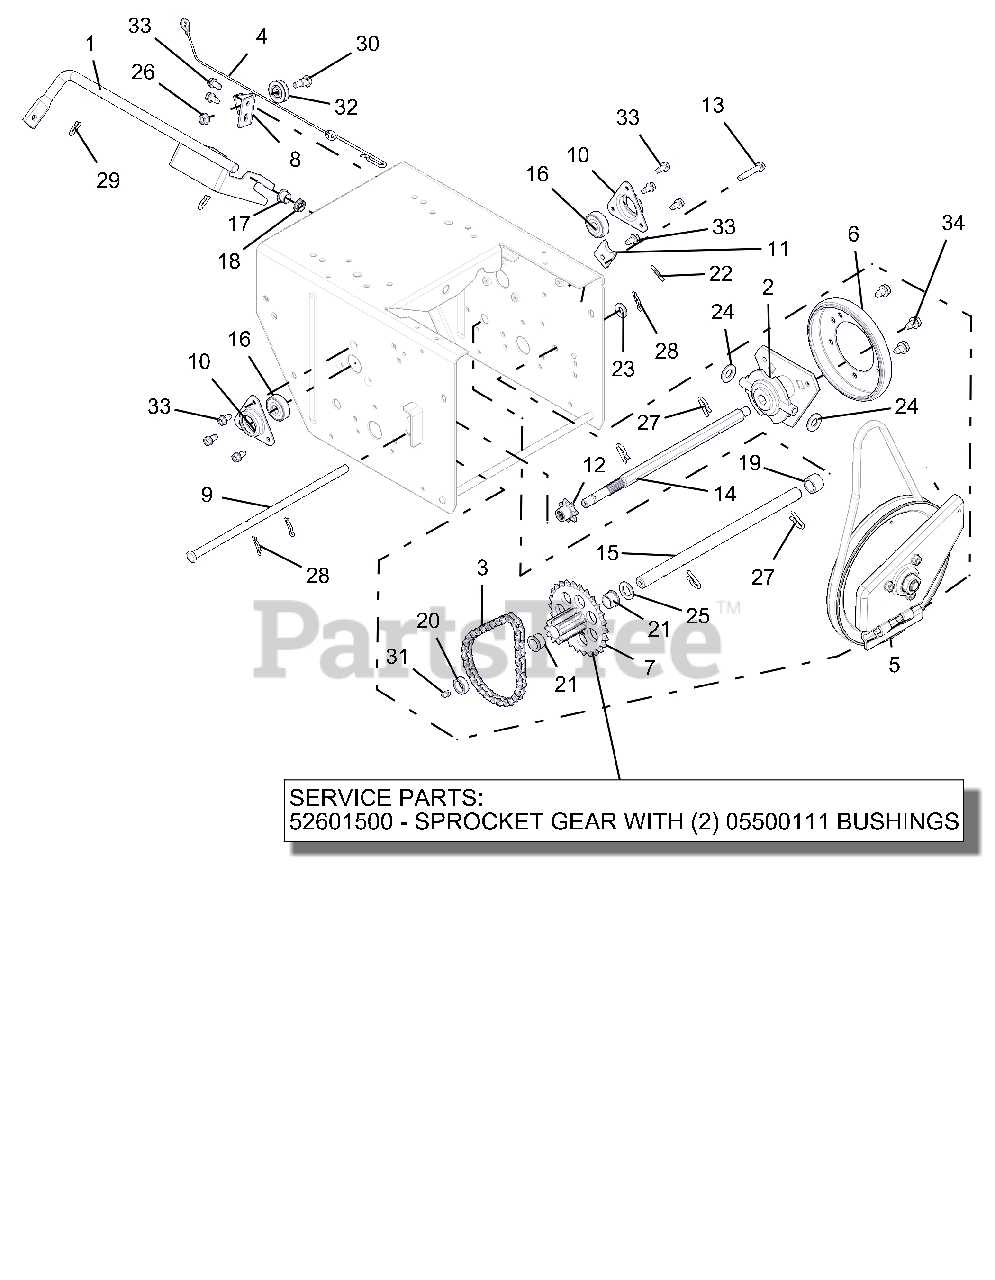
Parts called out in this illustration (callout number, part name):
1	ARM, SHIFT-WELDMENT
2	CARRIER, DRIVE DISK
3	CHAIN - #41, 32 PITCHES
4	CABLE, LOWER TRACTION,SS & PRO
5	PLATE, SWING ASSEMBLY-DEEP
6	FRICTION, DISC
7	PINION & SPROCKET
7	PINION & SPROCKET W/BUSHINGS
7	BSHG-FLG .625X.750X.500X.875
8	BRACKET, CABLE PULLEY
9	PIN, PIVOT
10	FLANGE, BEARING
11	TAB, ANTI ROTATION
12	SPROCKET, PINION 7T W/SPLINE
13	@SCR-TAP .25-20X1.50 HWH TR YZ
14	SHAFT, HEX-W/SPLINE TRACK
15	SHAFT, PINION - HARDENED
16	BRG-BALL .437X1.375X.437
17	BUSHING, POLYLINER-.50 SPLIT
18	BUSHING, POLYLINER-.50 SNAPIN
19	SPACER, .635X.880X.611
20	BSHG-SLV, .635X.880X.305
21	BSHG-FLG .625X.750X.500X.875
22	@PIN-GRV .125X1.00 TP E ALLOY
23	@WSHR-FL-STL.406X.812X.065 YWZ
24	WSHR-FL-STL .505X1.00X.062YWZC
25	WSHR-FL-STL .406X1.00X.188 YWZ
26	@NUT-LK-TOP-FLG .31-18 YWZC
27	PIN, SPRING CLIP
28	PIN-HAIR, ENDRIES #25 YWZC
29	CLIP, SPRING
30	BOLT, SHLDR-.375X.375X.25-20
31	ZERK,FITTING .25X.125 DRIVE IN
32	PULLEY, CABLE
33	SCR-TAP .25-20X.50 HWH TR YWZ
34	@SCR-TAP .31-18X.50 HWH TR YWZ
